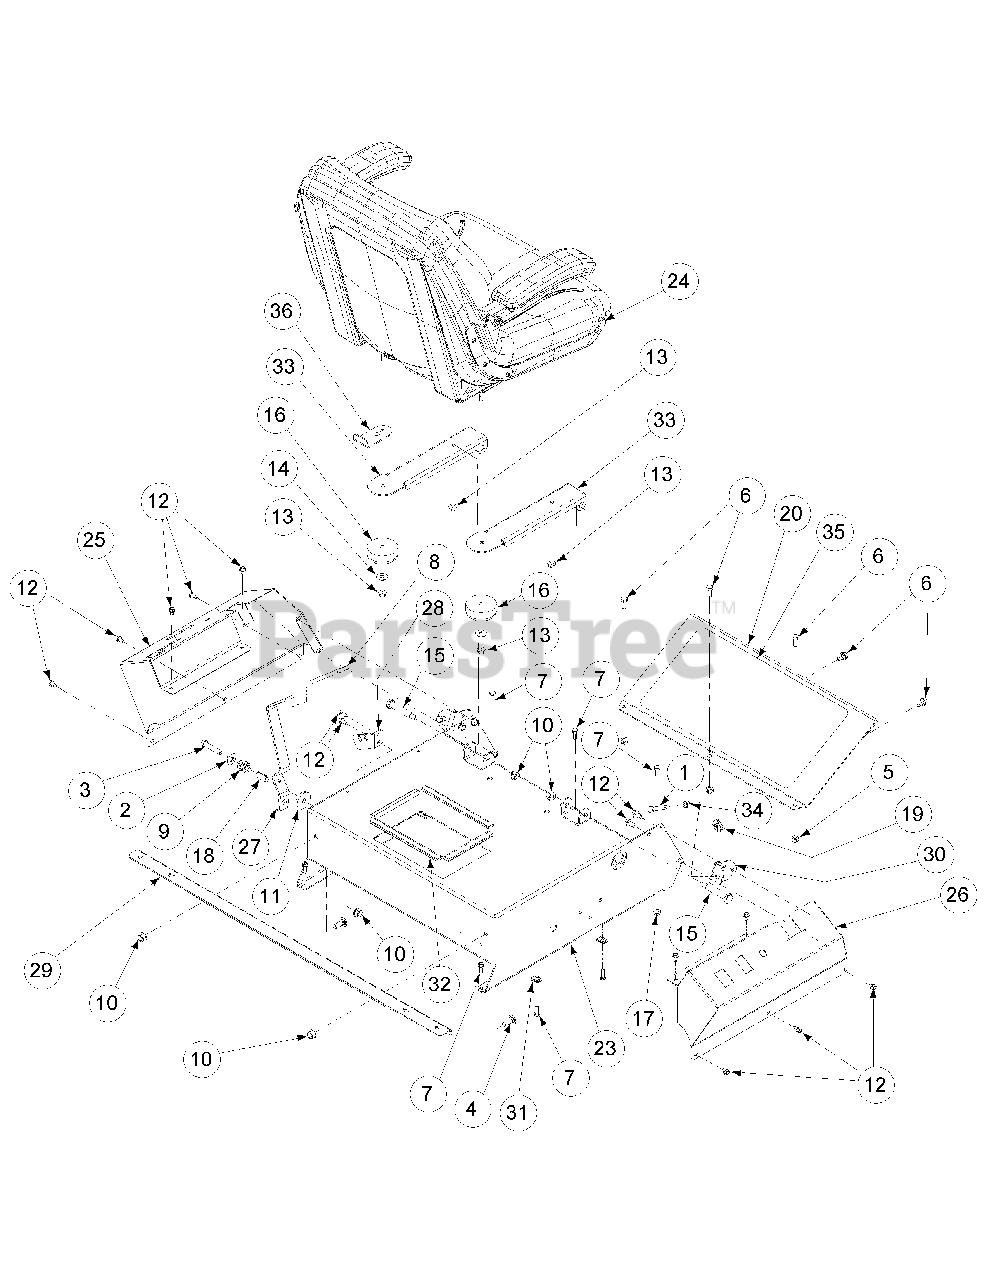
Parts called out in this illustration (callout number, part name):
1	Hex Cap Screw, 5/16-18 x 1-1/2
2	Idler Washer
3	Capscrew, 3/8-16 x 1-3/4
4	Carriage Bolt, 3/8-16
5	Nylock Nut, 5/16-18
6	Self Tapping Screw, 5/16-18 x 3/4
7	Self Tapping Screw, 1/4-20 x .75
8	Parking Brake Grip
9	Spring, .85 OD x 1 Lg
10	Hex Nut, 3/8-16 Flange Lock
11	Flat Washer, 1.25 x .411 x .100
12	Screw, 1/4-20 x 1/2
13	Hex Nut, 5/16-18 Flange Lock
14	Washer, .325 x .930 x .045
15	Shoulder Screw, 3/8-16, .5 x 2.345
16	Groment, 2.5 OD x 1.0 Lg
17	Hex Nut, 1/4-20 Flange Lock
18	Spacer, .375 x .50 x 1.02
19	U-Nut, 5/16-18
20	Foot Rest Bracket
23	Control Housing Weldment
25	Left Hand Control Console
26	Right Hand Control Console
27	Parking Brake Lever
28	Brake Cable Bracket
29	Front Tank Mounting Bracket
30	Lapbar Stop Bracket
31	U-Nut, 1/4-20
32	Battery Edge Trim
33	Seat Mounting Bracket
34	Hex Nut, 5/16-18
35	Abrasive Foot Pad
36	Seat Stop Bracket
